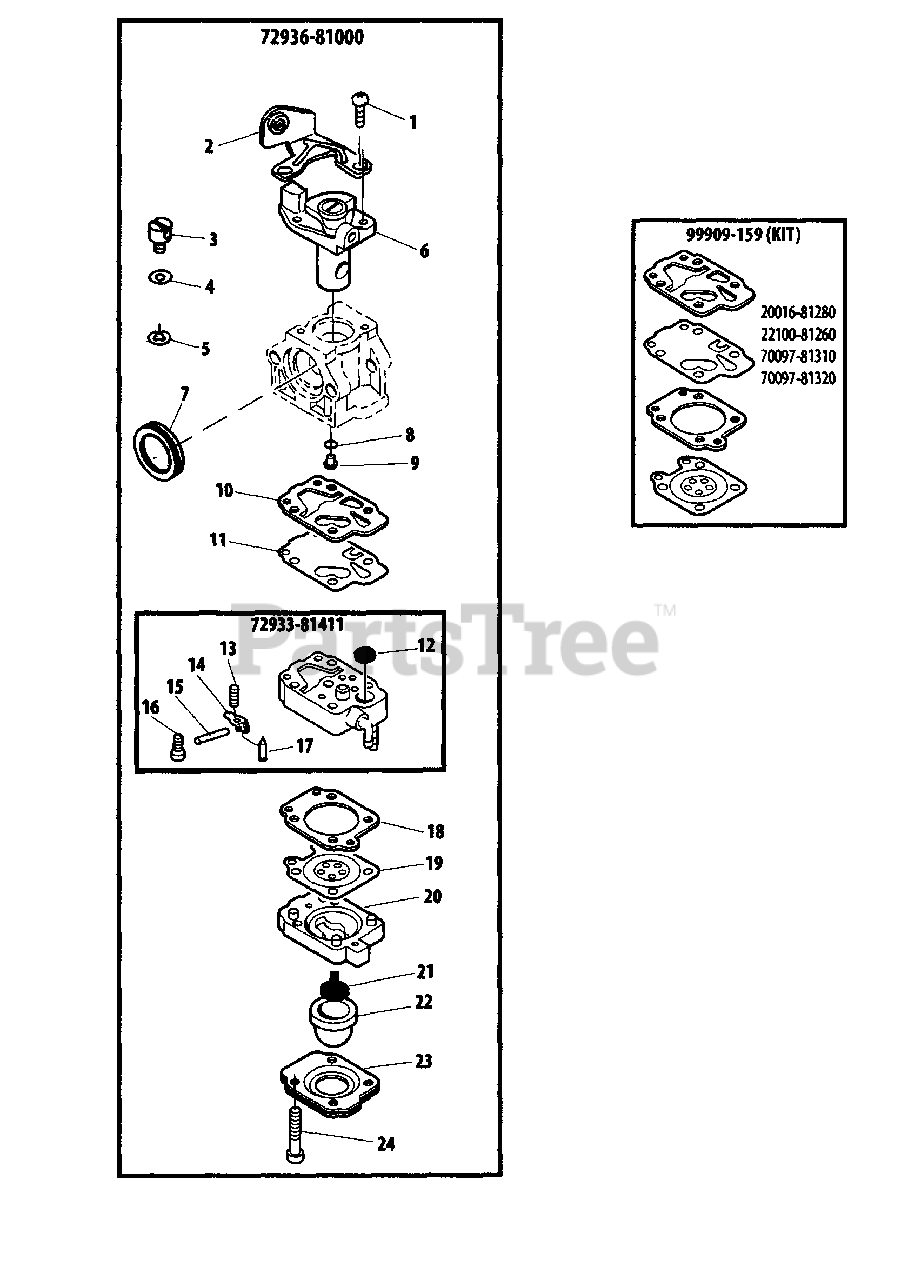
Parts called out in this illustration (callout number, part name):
1	SCREW
2	BRACKET, CABLE
3	SWIVEL
4	WASHER
5	RING, RETAINING
6	THROTTLE VALVE ASSY
7	SEAL
8	O-RING
9	JET
10	GASKET, PUMP
11	DIAPHRAGM, PUMP
12	STRAINER
13	SPRING, METERING LEVER
14	LEVER, METERING
15	PIN, METERING LEVER
16	SCREW, METERING LEVER PIN
17	VALVE, INLET NEEDLE
18	GASKET, METERING
19	DIAPHRAGM, METERING
20	BASE, PURGE
21	VALVE, CHECK
22	BULB, PURGE
23	RETAINER, PURGE BULB
24	SCREW, PUMP COVER
72933-81411	BASE, PURGE
72936-81000	CARBURETOR
99909-159	DIAPHRAGM/GASKET KIT
